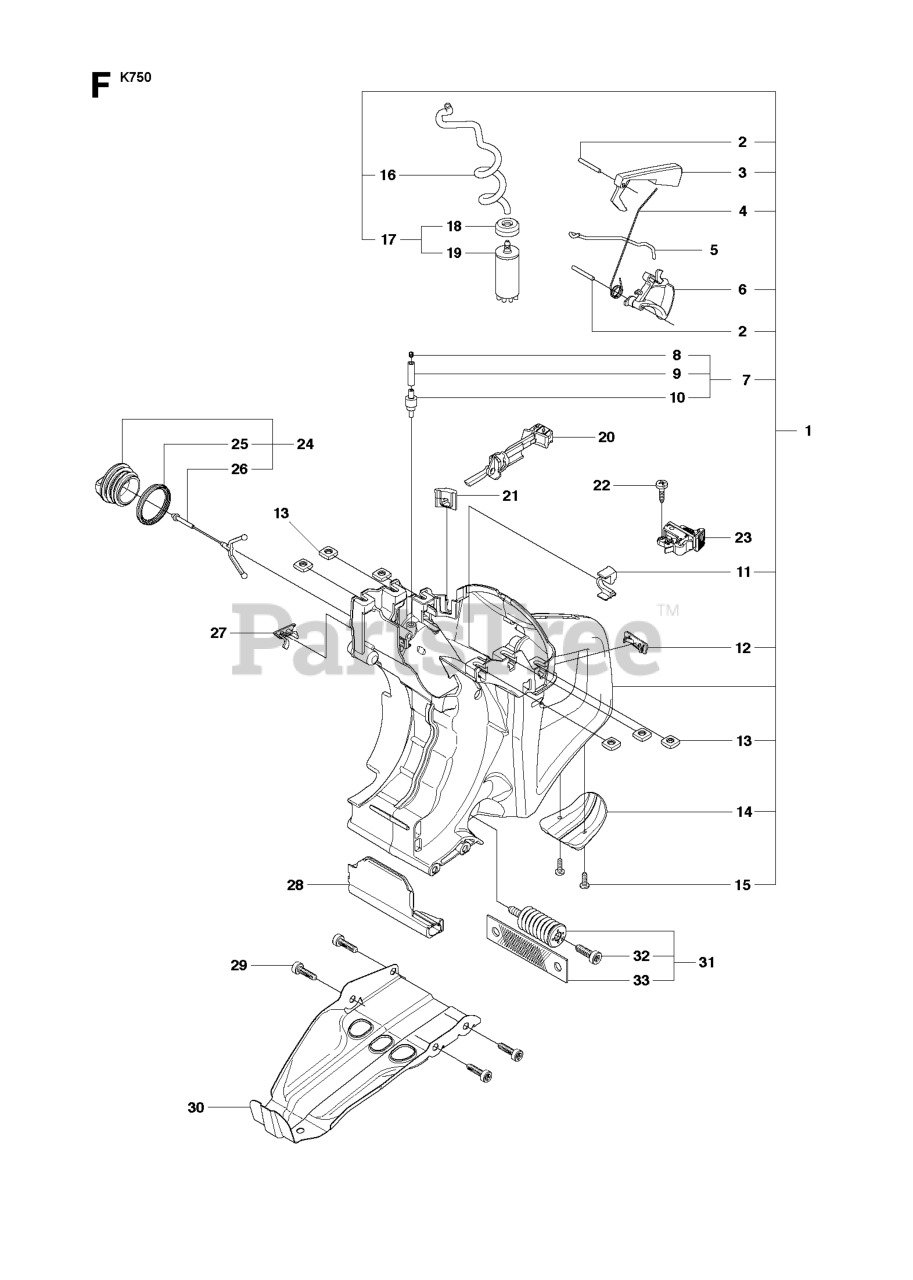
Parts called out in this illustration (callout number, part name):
1	RP FUEL TANK ASSY
2	PIN 3X25
3	THROTTLE LOCKOUT
4	SPRING
5	RP THROTTLE ROD
6	THROTTLE TRIGGER
7	TANK VENT ASSY
8	SINTER PLUG
14	GROUND SUPPORT
16	FUEL HOSE
20	CHOKE CONTROL
23	STOP SWITCH
24	TANK CAP ASSY
28	HEAT SHIELD
30	BASE PLATE
31	VIBRATION ABSORBER
